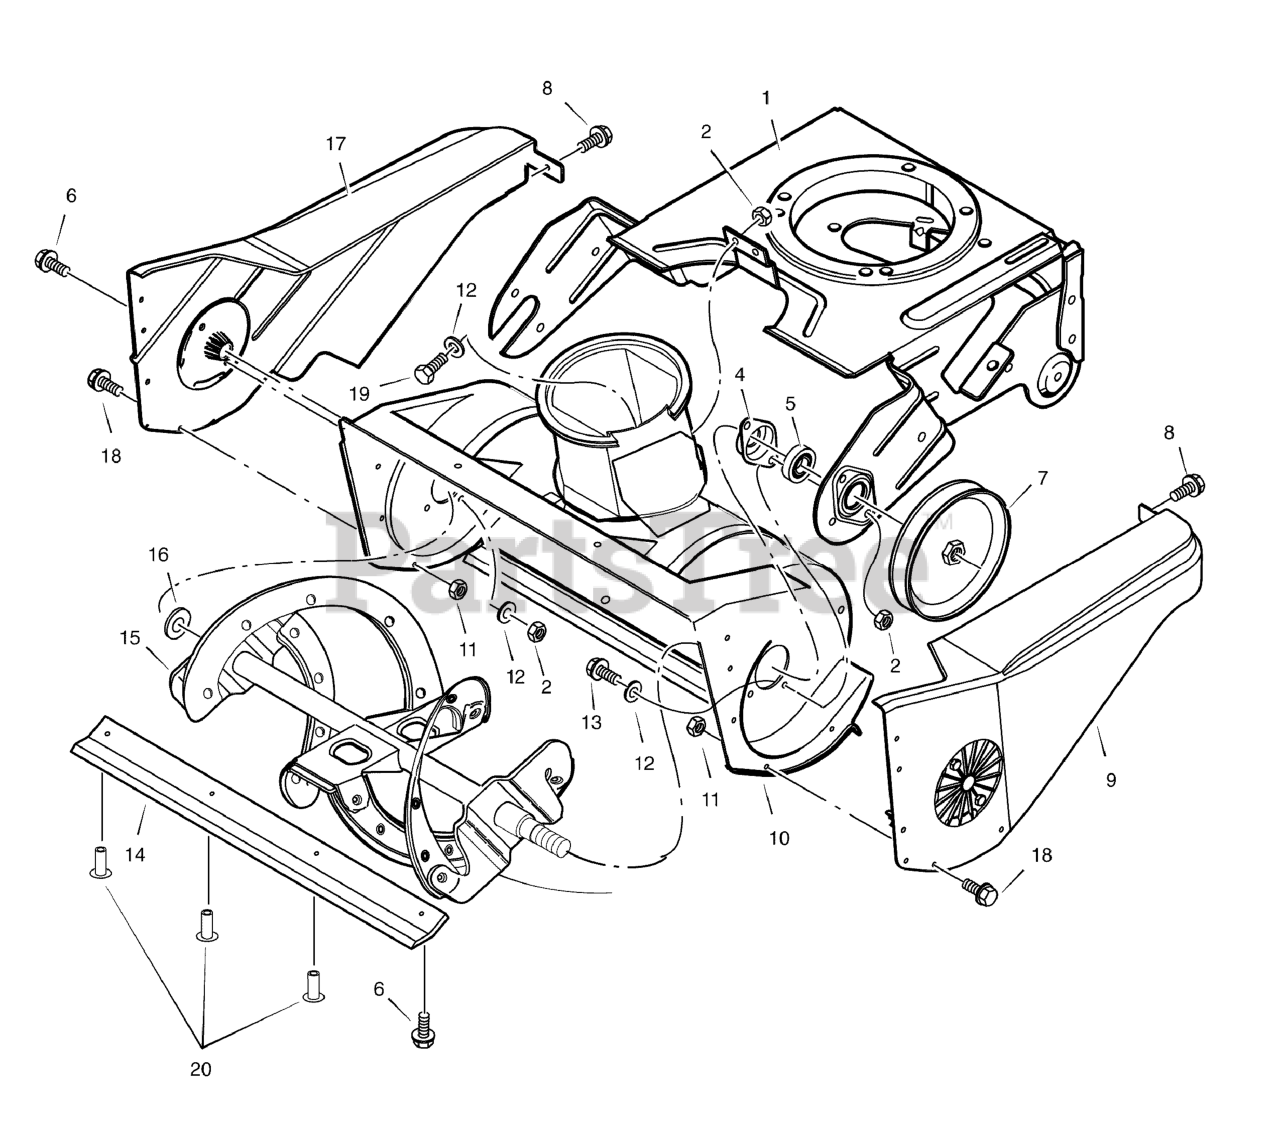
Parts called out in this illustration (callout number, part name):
1	Frame, Motor Box
4	Retainer, Bearing
5	Bearing
7	Pulley, Auger
9	Cover, Left Belt
10	Assembly, Auger Housing
11	Nut
12	Washer
14	Blade, Scraper
15	Auger Assembly
17	Cover, Right
